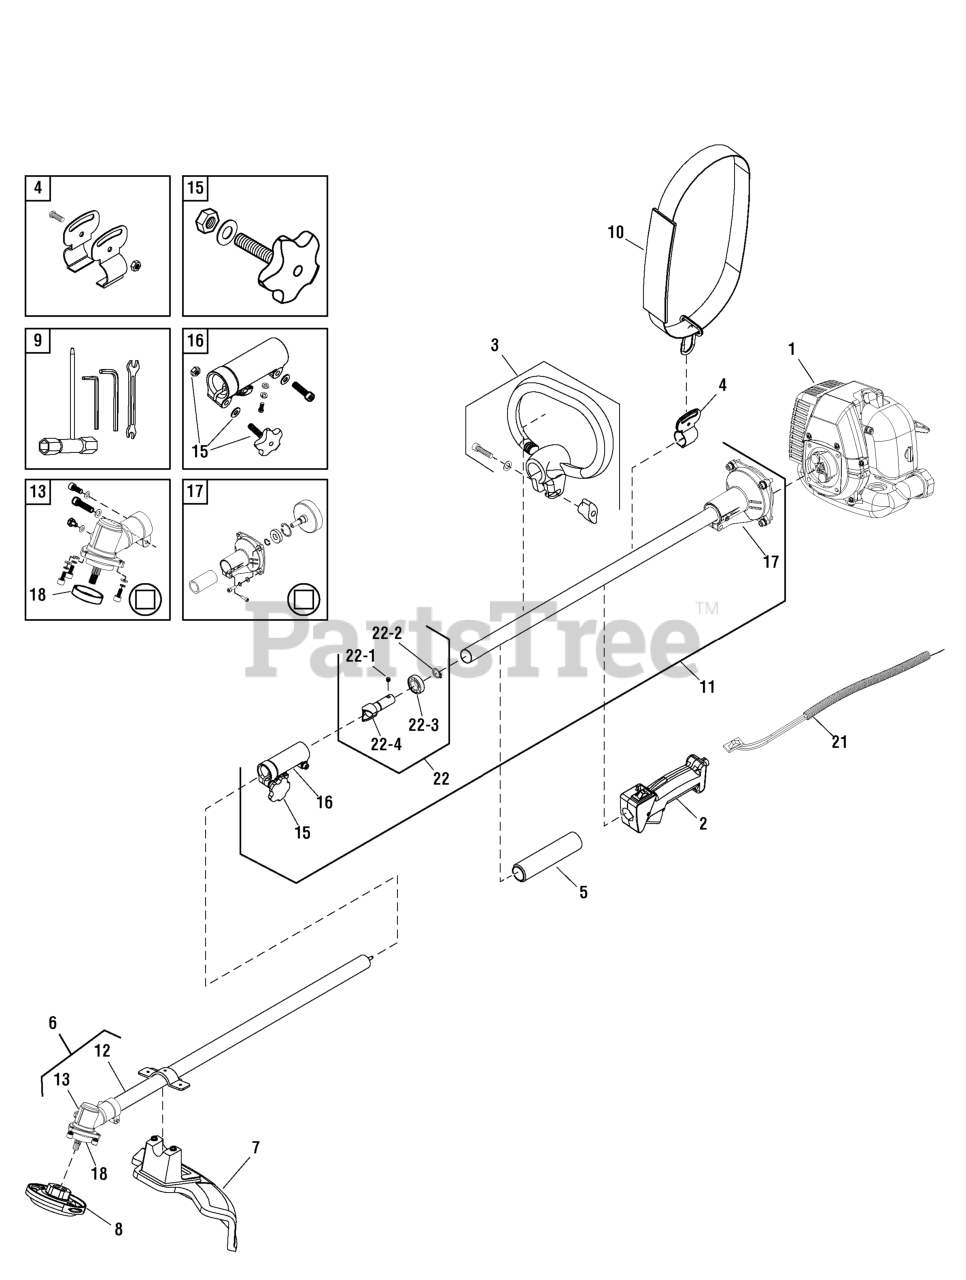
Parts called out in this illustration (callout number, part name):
1	ENGINE, 26cc 2 Stroke
2	TRIGGER HOUSING ASSEMBLY
3	HANDLE ASSEMBLY
4	BRACKET, Strap
5	POLE PAD
6	SHAFT & GEAR HEAD ASSEMBLY, Lower, Straight
7	GUARD ASSEMBLY, Straight Shaft
8	TRIMMER HEAD
9	TOOL KIT, Trimmer
10	HARNESS, Shoulder
11	SHAFT ASSEMBLY, Upper
12	SHAFT ASSEMBLY, Lower, Straight
13	HOUSING, Gearbox, Flex Straight Shaft, Square Drive
15	KNOB ASSEMBLY
16	COUPLING ASSEMBLY, Easy Link (Easy Link Drive System)
17	CLUTCH & HOUSING ASSEMBLY, Square Drive
18	WASHER, Mount, Straight Shaft
21	THROTTLE CABLE, Sleeve & Switch, Red
22	EASY LINK SOCKET & BEARING ASSEMBLY
22-4	DRIVE SOCKET
